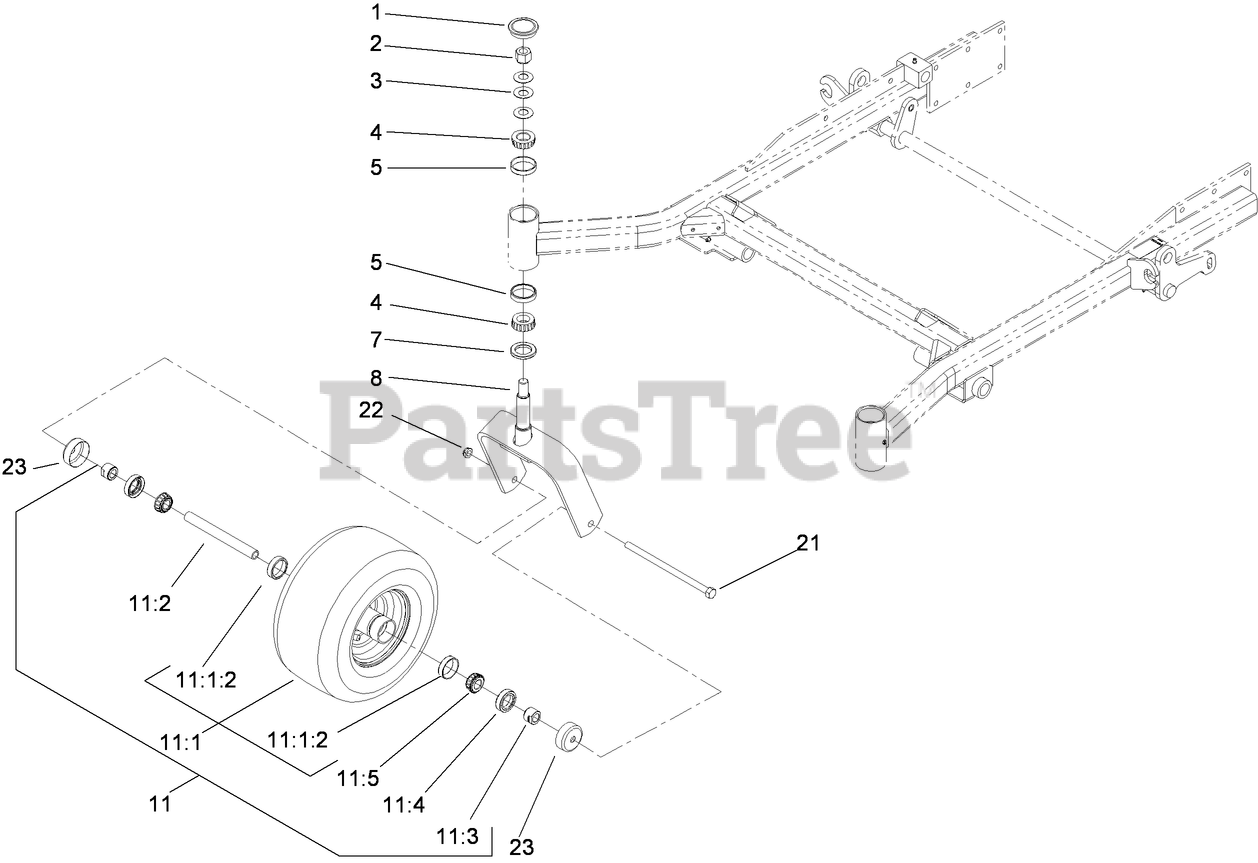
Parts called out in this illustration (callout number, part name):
1	CAP-GREASE
2	NUT-LOCK, NI
3	WASHER-BELLVILLE
4	BEARING-CONE, TAPERED
5	BEARING-CUP, TAPERED
7	SEAL-GREASE
8	CASTER-FORK
11	WHEEL ASM
11:1	WHEEL AND TIRE ASM
11:1:2	BEARING-CUP
11:2	Axle-Caster
11:3	SPACER-NUT
11:4	SEAL-CASTER
11:5	BEARING-CONE, TAPER
21	Screw-HH
22	NUT-LOCK, NI
23	GUARD-SEAL
